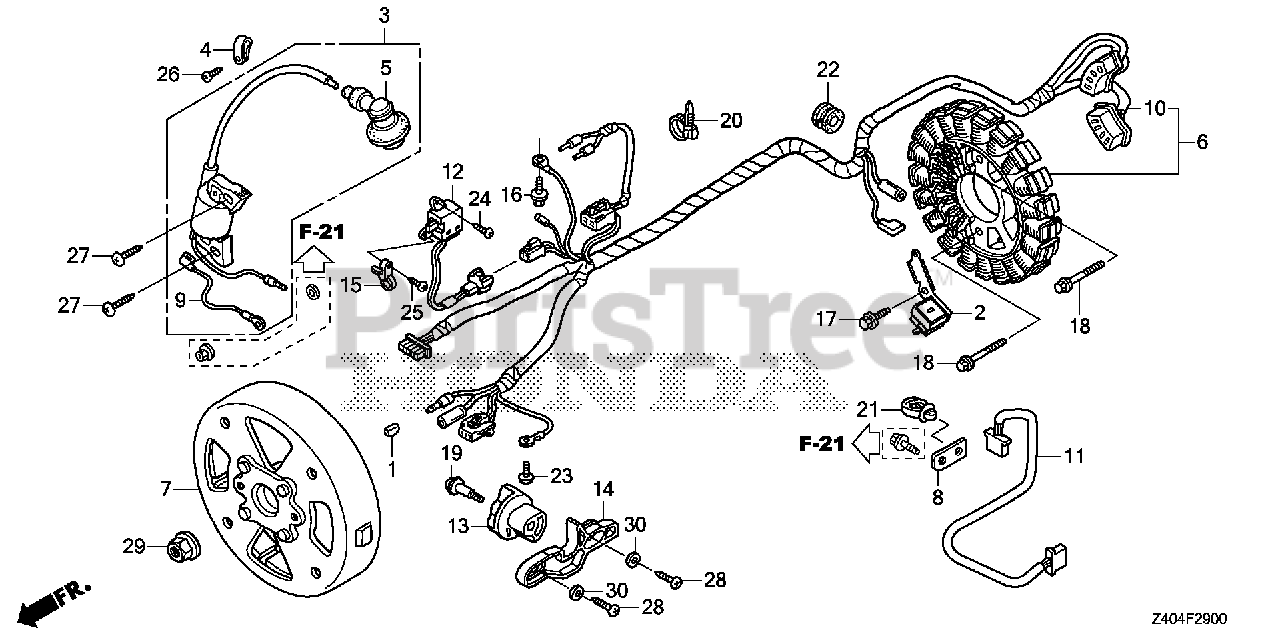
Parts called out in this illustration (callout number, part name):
1	KEY, SPECIAL
2	COIL, PULSER
3	COIL ASSY., IGNITION
4	CLAMP A, CABLE
5	CAP ASSY., NOISE SUPPRESSOR
6	STATOR ASSY.
8	BRACKET, WIRE HARNESS CLIP
9	WIRE, IGNITION GROUND
10	WIRE HARNESS ASSY., GENERATOR
11	SUB-WIRE ASSY.
12	SWITCH ASSY., ENGINE STOP
13	KNOB, ENGINE SWITCH
14	PLATE, ENGINE SWITCH
15	BAND, HARNESS
16	BOLT, FLANGE (5X8)
17	BOLT, FLANGE (5X12)
18	BOLT, FLANGE (5X25) (CT200)
19	SCREW, PAN (4X19)
20	BAND, WIRE (BLACK)
21	CLIP, WIRE HARNESS (25MM)
22	GROMMET, GENERATOR CORD
23	SCREW, PAN (5X8)
24	SCREW, TAPPING (3X10) (NOT AVAILABLE)
25	SCREW, TAPPING (3X16)
26	SCREW, TAPPING (5X12)
27	SCREW, TAPPING (6X20)
28	SCREW, TAPPING (5X20) (PO)
29	NUT, FLANGE (10MM)
30	WASHER, PLAIN (5MM)
